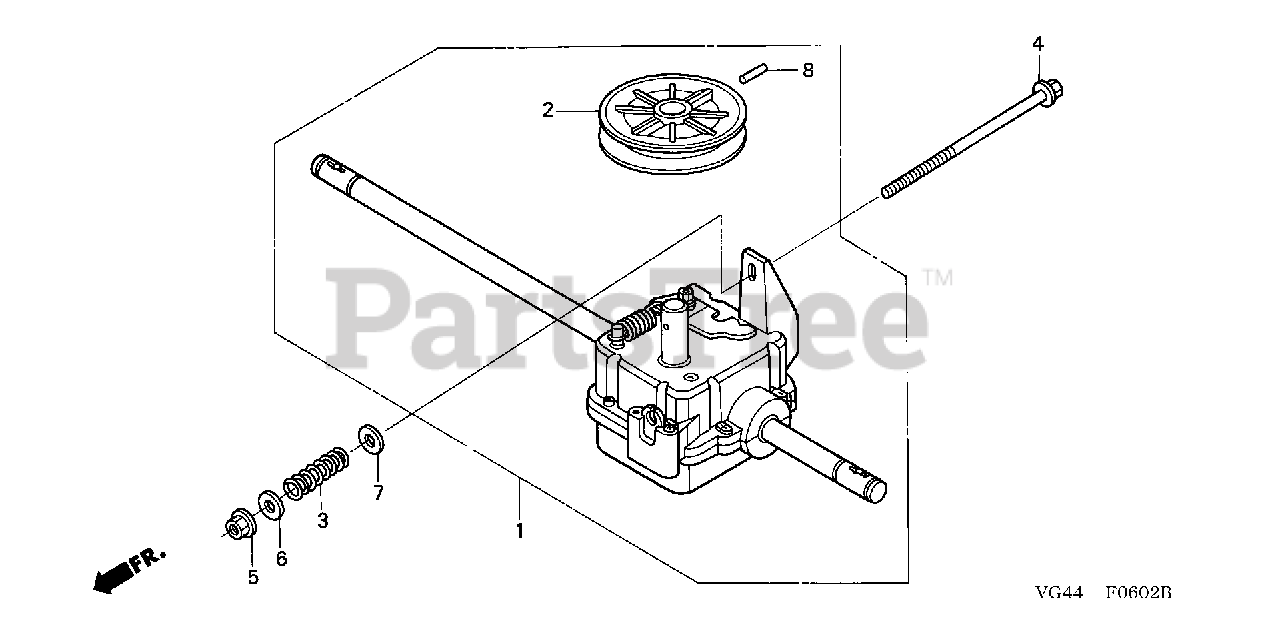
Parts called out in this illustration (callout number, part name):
1	TRANSMISSION ASSY.
2	PULLEY, DRIVEN
3	SPRING, BELT TENSIONER
4	BOLT, FLANGE (6X135)
5	NUT, NYLON LOCK (6MM)
6	WASHER, PLAIN (8MM)
7	WASHER, PLAIN (6MM)
8	PIN, SPRING (5X36)
